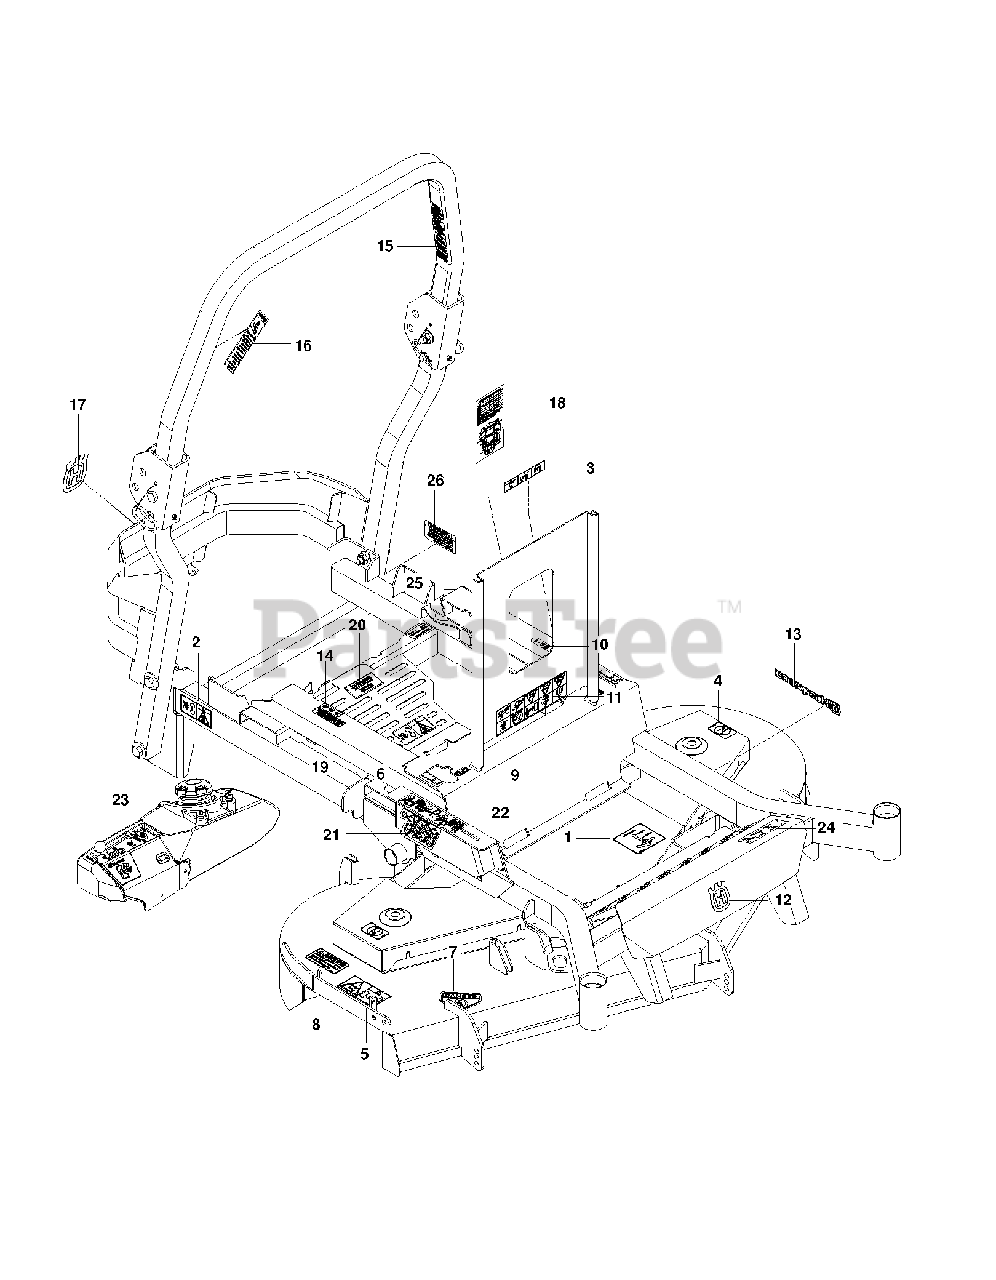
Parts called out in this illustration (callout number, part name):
1	DECAL, BELT ROUTING
2	DECAL, BELT DRIVE
3	EURO DECAL-BATTERY WARNIN6
4	DECAL, NO STEP
5	DECAL, EURO SEVERING
6	DECAL, MOTION CONTROL
7	DECAL, CPSC
8	DECAL, CAUTION
9	DECAL, F.S.T.
10	DECAL, PARK BRAKE
11	DECAL, WARNING
12	DECAL.AUGER.HUSQ.CROWN.SNOW
13	RP.DECAL.BADGE.170MM.TEXTLOGO
14	DECAL, FUSE
15	DECAL, ROPS
16	DECAL, ROPS, WARNING
17	DECAL, CROWN H, 110MM
18	DECAL, SERVICE
19	DECAL, WARNING SPARK ARRESTOR
20	HG_DECAL, ZT-3400
21	DECAL, HEIGHT
22	DECAL, RELEASE LEVER
23	DECAL, CONTROL, GAS
24	DECAL P-ZT 48
25	DECAL, FUEL
26	DECAL, PROP. 65
